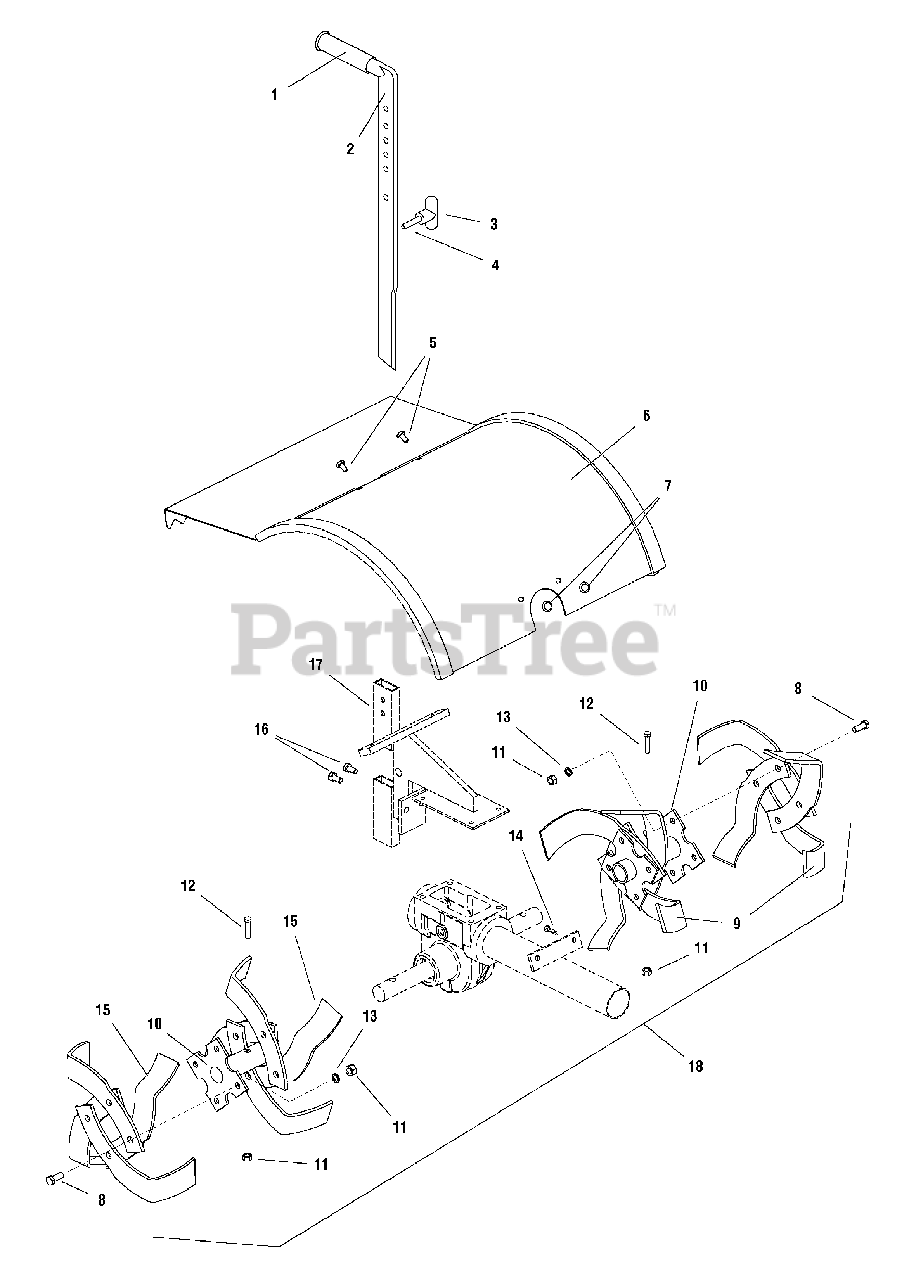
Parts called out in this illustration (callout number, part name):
1	GRIP, Handle, Black
2	LEVER, Drag Stake, Walk-Behind Tiller
3	KNOB, T Handle, Drag Stake
4	PIN, DETENT, 5/16"- 18 x 1"
5	CAPSCREW, 1/4"- 20 x 1/2" G5
7	NUT, Hex Flange 5/16"- 18 Two, Way Lock
8	CAPSCREW, 3/8"- 16 x 1" G5
9	TINE BLADE, Left Side
10	HOLDER, Tine Blade LH+RH
11	NUT, Hex 3/8"- 16NC
12	CAPSCREW, 3/8"- 16 x 1-3/4" G5
13	LOCKWASHER, Spring 3/8"
14	CAPSCREW, 5/16"- 18 x 1" G5
15	TINE BLADE, Right Side
16	CAPSCREW, Hex Flange Head, 5/16"- 18 x 1/2"
17	BRACKET, Depth Regulator RT
18	REPLACEMENT KIT, Tine Blade Holder
